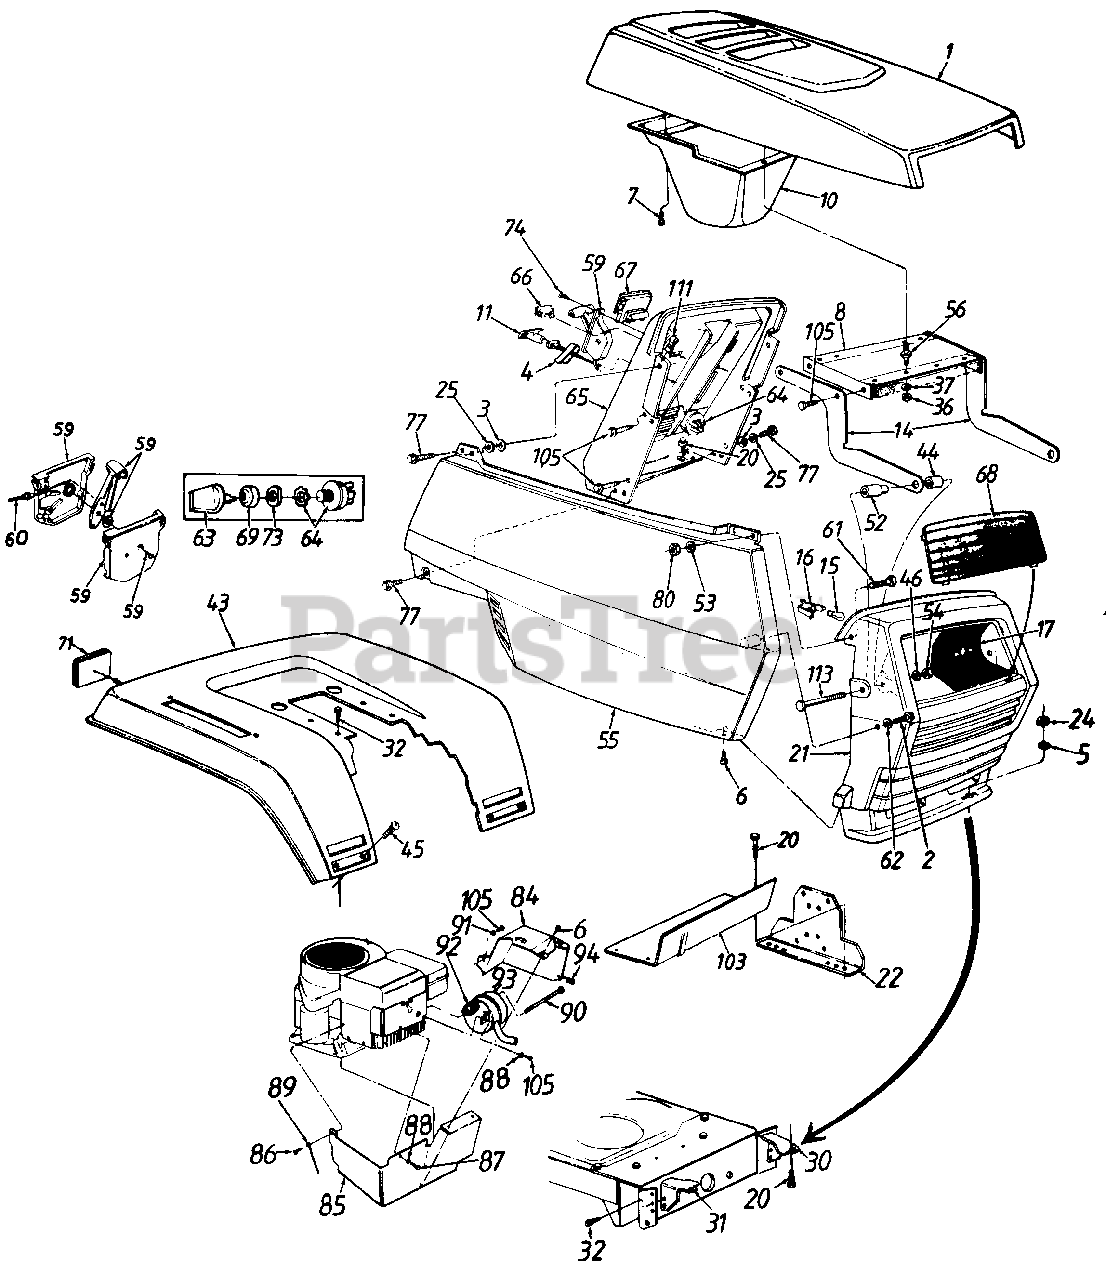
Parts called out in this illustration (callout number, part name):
3	Bolt Retainer 1/4" I.D.
4	Retainer Clip
5	Fl-Wash. .34" I.D. x .68"
6	Truss Mach. AB-Tap Scr. #10 x 5" Lg.
7	Hex Wash Hd. AB-Tap Scr. #8 x .5, Lg.
8	Hood Plate
11	Choke Control 29" Lg.
14	Hood Hinge
15	Lamp
16	Twist Lock-Lamp Socket
17	Reflector-Headlight
20	Hex Bolt 5/16-18 x .75" Lg.
21	Grille
24	Hex Nut 5/16-18 Thd.
25	Fl-Wash. 1/4" I.D. x .93" O.D.
30	Grille Mount Brk't.-L.H.
31	Grille Mount Brk't.-R.H.
32	Hex Wash. Hd. AB-Tap Scr. 5/16 x .75" Lg.
36	Hex Nut 1/4-20 Thd.
37	Bell-Wash. .265" I.D. x 75n
45	Carriage Bolt 1/4-20 x .50" Lg.
46	Fl-Wash. .328" I.D. x .68" O.D.
52	Shld. Spacer .33" I.D.
53	Fl-Wash. .281" I.D. x .5" O.D.
54	Hex Cent. L-Nut 5/16-18 Thd.
55	Side Cover-R.H.
56	Double Ended Stud 1/4-20 Thd.
59	Throttle Control Box Ass'y.
60	Throttle Control Wire 18.5" Lg.
61	Hex Bolt 1/4-20 x .62" Lg.
62	Fl-Wash. .281" I.D. x 73n O.D.
64	Ignition Switch
65	Dash Panel
66	Light Switch
67	Ammeter
68	Lens
69	Ignition Switch Cap
71	Reflector
73	Ignition Switch Nut
74	Truss Mach. AB-Tap Scr. #10 x .5" Lg.
77	Hex Wash. Hd. Tap Scr. 1/4 x.75" Lg.
80	Hex L-Nut 1/4-20 Thd.
84	Muffler Heat Shield-L.H.
85	Muffler Heat Shield-Front
86	Truss Mach. Scr. 5/16-18 x 75" Lg.
87	Hex Bolt 1/4-20 x 3/8" Lg.
88	Spr. Wash. .265n l.D. x .562"
89	Engine Ground Wire
90	Shld. Bolt 7/16n Dia. x 3-5/8" Lg.
91	L-Wash. 1/4" I.D.
92	Gasket
93	Muffler
94	Speed Nut #10-24 Thd.
103	Gasoline Tank Support
105	Hex Tap Scr. 1/4-20 x .5" Lg.
111	Speed Nut 1/4-20 Thd.
113	Hex Bolt 5/16-18 x 2.75"
